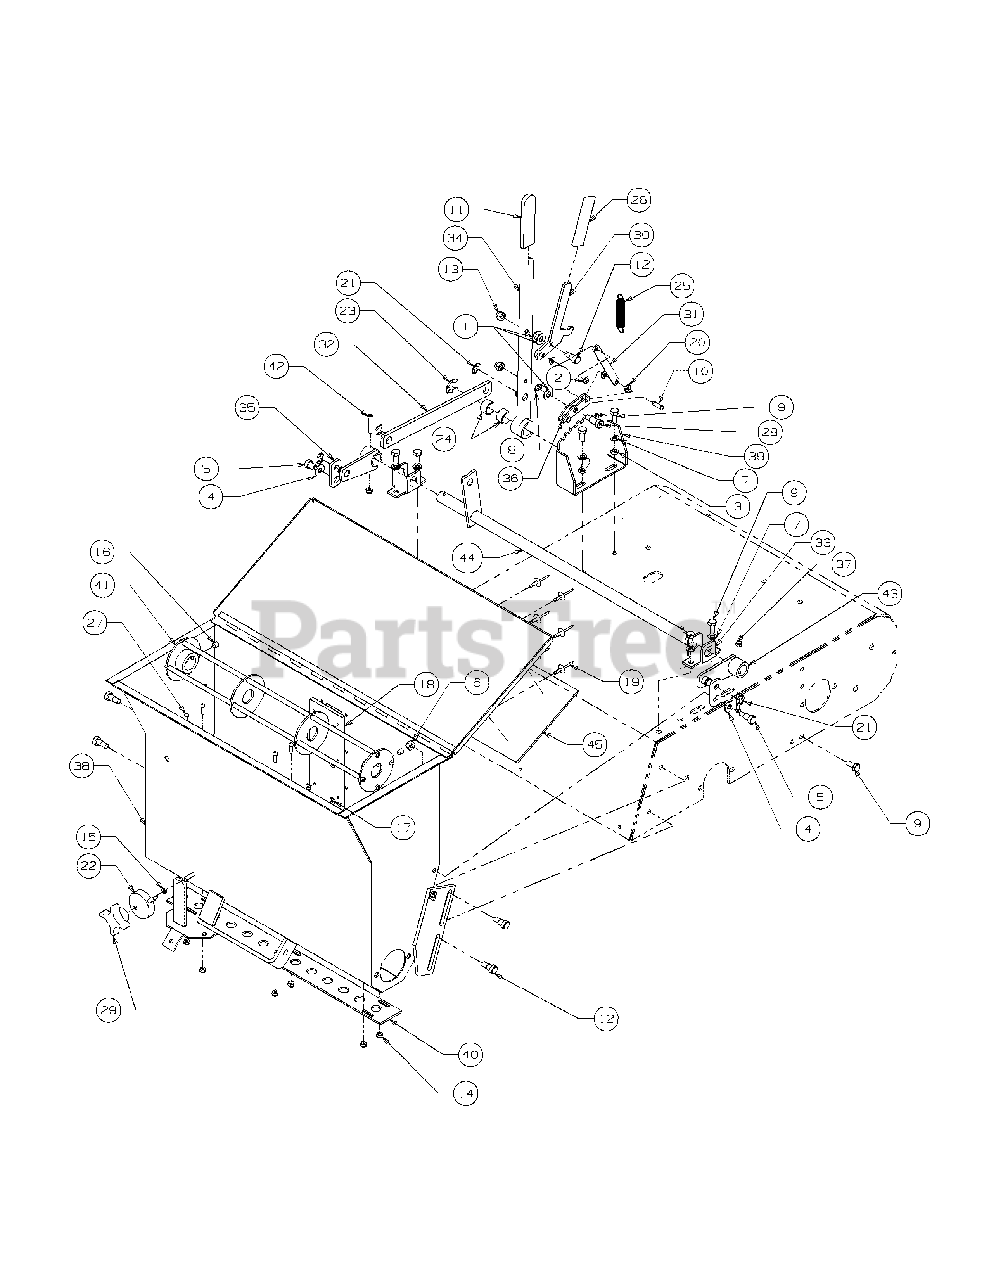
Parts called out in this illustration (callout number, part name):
1	Flat Washer, Nylon, 3/8
2	Retainer Clip, "C"
3	Flat Washer, 5/16
4	Flat Washer, 3/8
5	Socket Shoulder Bolt, 3/8 x 12
6	Nylock Nut, 5/16-18
7	Lock Washer, 5/16
8	Flat washer, 5/16
9	Hex Cap Screw, 5/16-18 x 3/4
10	Clevis Pin, 1/4 x 3/4
11	Grip, .250 x 1.0 x 4
12	Shoulder Bolt, 3/8 x 3/8
13	Acorn Nut, 5/16-18
14	Lock Nut, Nylon Insert, #10-32
15	Flat Washer, 1/4
16	Cap Screw, 5/16-18 x 5/16
17	Flat Washer, 3/16
18	Clear Plate
19	POP Rivet, 3/16
20	Nylon Washer, 1/4
21	E-Ring, 1/2"
22	Hopper Dial Assembly
23	E-Ring, Retainer
24	Sintered Bearing
25	Spring Reel Enlargement
26	Grip, 3.5"
27	Machine Screw, 10-32 x 5/8
28	Shoulder Bolt, 3/8 x 5/8
29	Knob Control Rate
30	Hopper Lift, Pivot Assembly
31	Hopper Lift, Link, Short
32	Hopper Lift, Link, Long
33	Hopper Assembly, Lift Support
34	Hopper Lift, Handle Assembly Bearing
35	Hopper Lift, Link
36	Hopper Lift, Latch Assembly
37	Nylon Lock Nut, #10-24
38	Hopper Assembly Cover
39	Hopper Lift, Bracket Assembly
40	Metering Bar Assembly
41	Agitator Assembly
42	Socket Screw, #10-24 x 1.25
43	Hopper Lift, Arm Assembly
44	Hopper Lift Assembly
45	Step, 6'' Roll Saftey Adhesive
